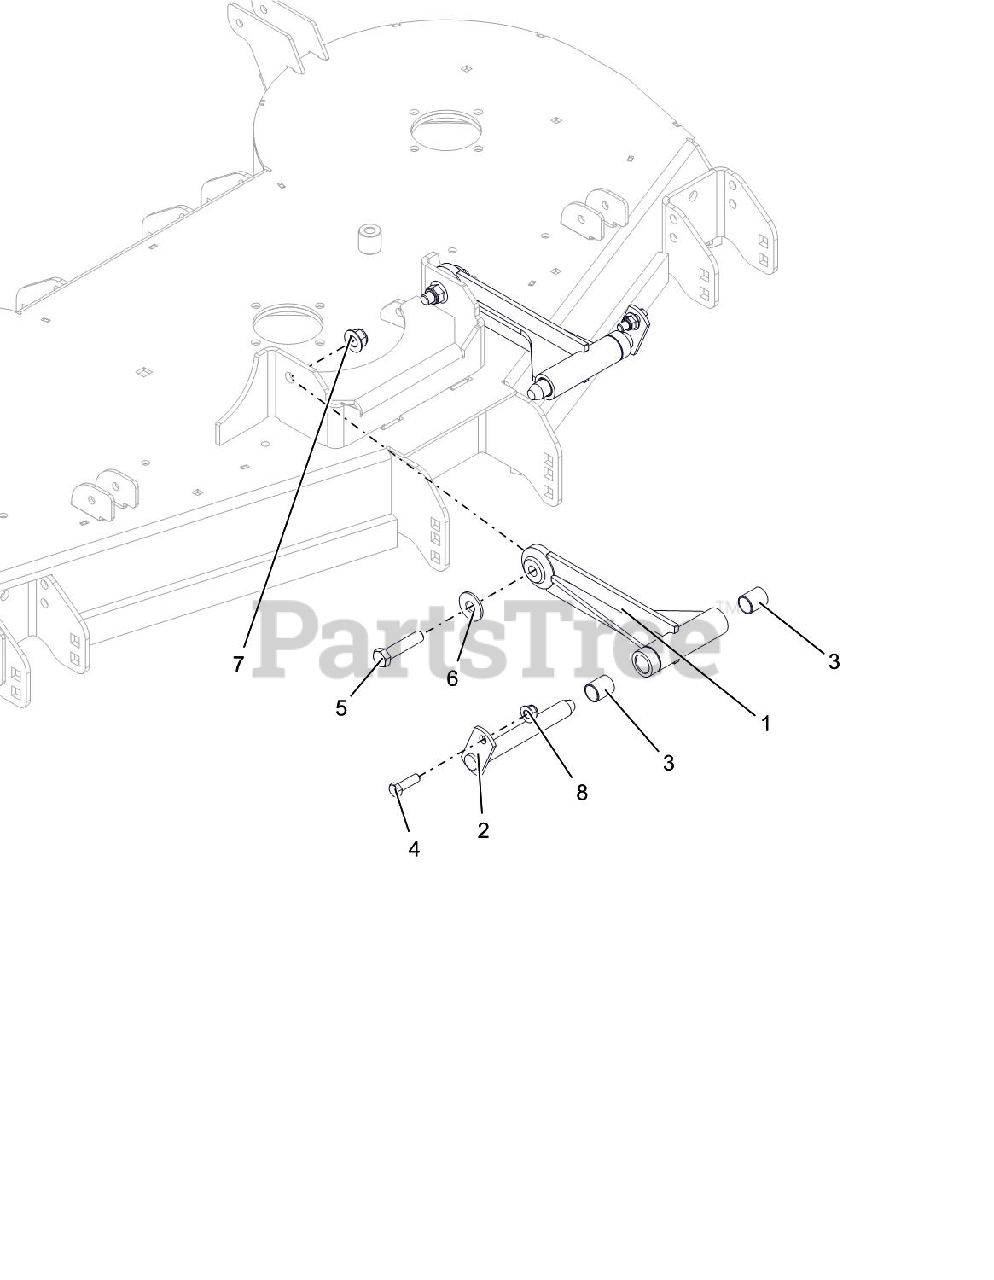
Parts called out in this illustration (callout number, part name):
1	WMT, DRAG LINK
2	WELDMENT, MOWER MTG. PIN
3	BRG, .750 X .875 X 1.000
4	@BLT-HEX .38-16X1.25 GR5 YWZC
5	@BLT-HEX .50-13X2.25 GR5 YWZC
6	@WSHR-FL-STL.563X1.38X.109YWZC
7	@NUT-LK-NYL-FLG .50-13 YWZC
8	@NUT-LK-NYL-FLG .38-16 YWZC
